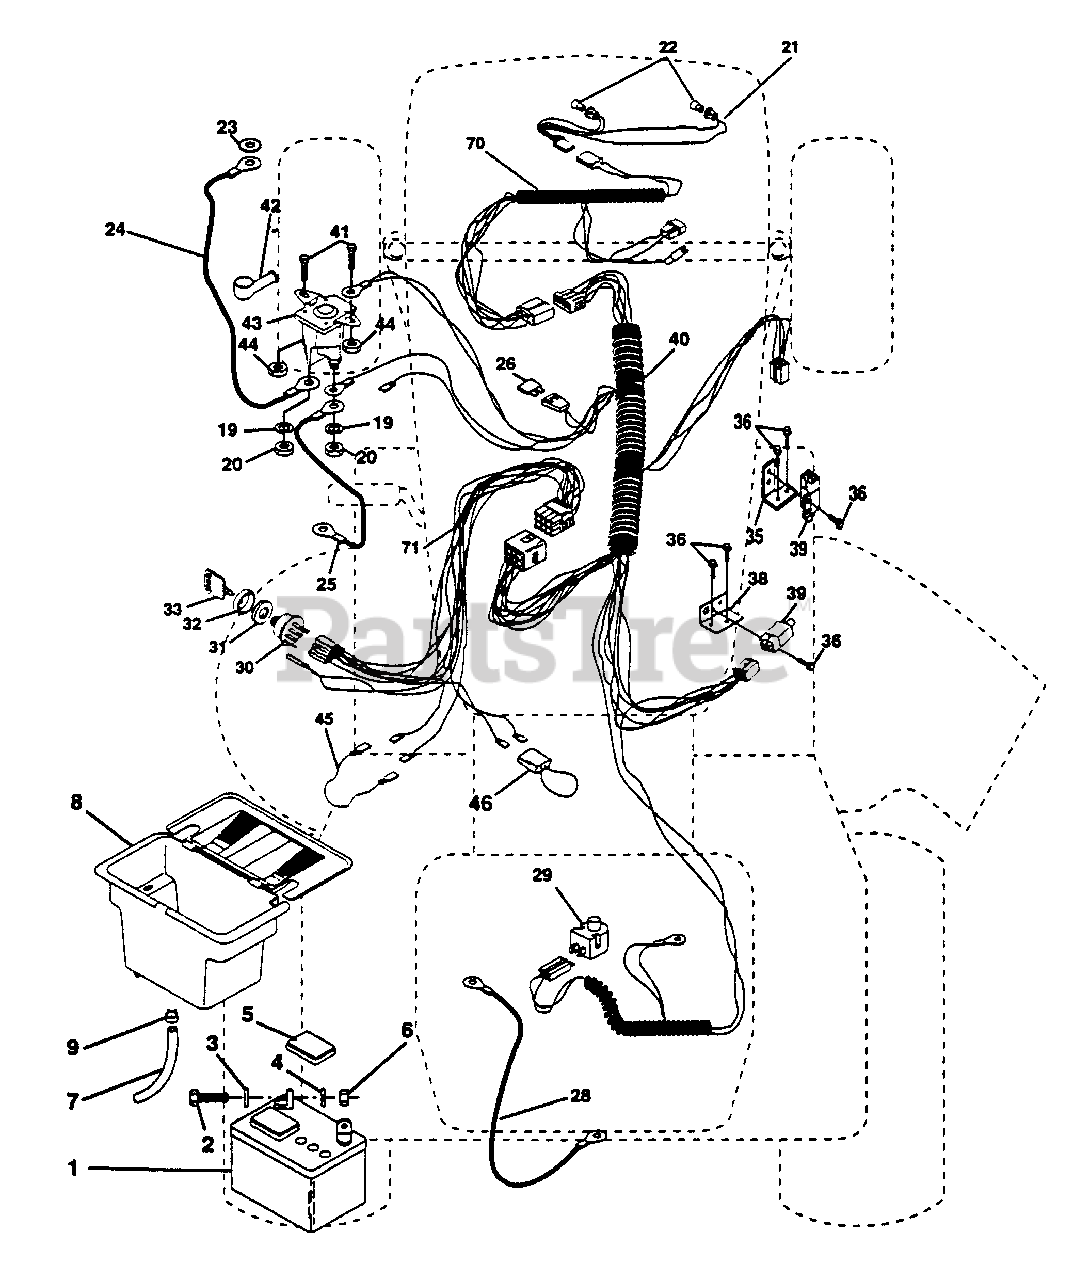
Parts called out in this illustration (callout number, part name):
1	Battery 12 Volt 25 AMP
2	Bolt Hex Hd 1/4-20unc X 3/4
3	Washer 9/32 X 5/8 X 16 Ga.
4	Washer Lock H Helical 1/4
5	Caps Battery 20/25/30 AMP
6	Nut Fin Hex 1/4-20 Unc
7	Tube Plastic 12"
8	Case Battery Hng Mech W/lid
9	Clamp Hose Olive
19	Washer Lock 1/4
20	Nut Jam Hex 1/4-20 Unc
21	Harness Asm Light W/4152j
22	Bulb Light #1156
23	Washer Lock Internal Tooth 1/4
24	Cable Battery 6 Ga 11" red
25	Cable Battery 6 Ga 43" red
26	Fuse 30 AMP Auto Green
28	Cable Ground 6 Ga 12" black
29	Switch Plunger Nc Gray
30	Switch Ign 4 pos w/lights
31	Nut Ignition
32	Cover Sw Ignition
35	Bracket Switch Clutch
36	Screw Tap Hex #10-24unc X 1/2
38	Bracket, Switch, Interlock
39	Switch Intlk Clutch Red 4 Term
40	Harness Chassis LT PL Mech
41	Bolt Blk Fin Hex 1/4 - 20 x 1/2
42	Cover Terminal Red
43	Solenoid
44	Nut Keps Hex 1/4-20 Unc
45	Adapter Ammeter Rectangular
46	Protection Wire Loop
70	Harness, Eng.
71	Harness Dash Lt Private Lbl
